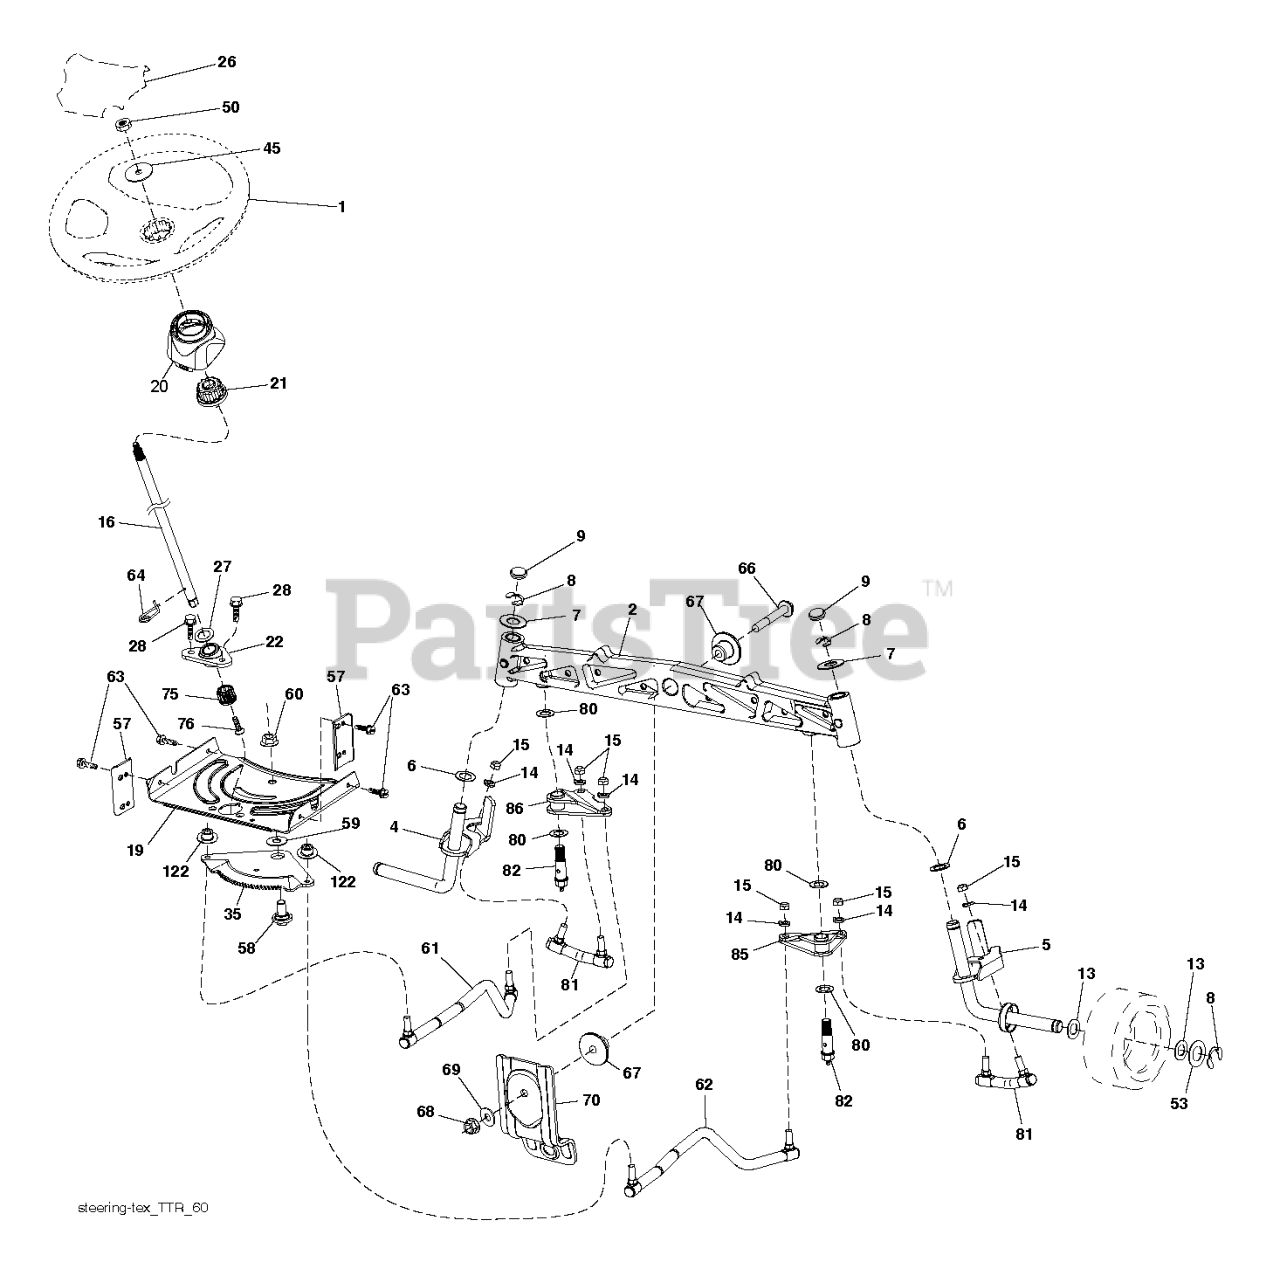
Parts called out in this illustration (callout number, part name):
1	WHEEL.STEERING.HARD.RIM.BLAC
2	RP SUBASM.AXLE.CAST.NZTR.
4	SPINDLE WELDMENT.SPINDLE.LH.15
5	SPINDLE WELDMENT.SPINDLE.RH.15
6	Bearing Race Thrust Harden (AYP part number)
7	Washer 25/32 x 1-5/8 x 16 Gauge (AYP part number)
8	Ring, Klip #T5304-75 (AYP part number)
9	Cap Spindle Fr Top Blk (AYP part number)
13	Washer 25/32 x 1-1/4 x 16 Gauge (AYP part number)
14	SLW 3/8 STD
15	Nut, Crownlock 3/8-24 (AYP part number)
16	SHAFT.STEER.2HIGH.SPLND.PLATED
19	PLATE.STEER.DDL.NLT/NG
20	BOOT.STRNG.PREDATOR.YT/GT.428
21	ADAPTER.WHEEL.STEER.SPLND.ALUM
22	BEARING.SHAFT.STEER.LOWER.625
26	INSERT, WHEEL STEERING
27	Washer 21/32 x 1 x 16 Gauge (AYP part number)
28	SCREW, 3/8-16X3/4
35	GEAR GEAR.SECTOR.TEX.NZTR
45	WASHER.3/8ID.2-3/8OD.12GA.PLTD
50	NUT LOCK FLG 3/8-16 UNC
53	WASHER.HARDENED
57	BRACKET.UPSTOP.TEX
58	BOLT.SHOULDER.SECTOR.P
59	WASHER.THURST.SECTOR.S
60	NUT FLANGE LOCK 5/8-11
61	LINK SUBASM.LINK.DRAG.LH.NZTR
62	TUBE TUBE
63	SCREW
64	RETAINER.CLIP.SPRING.S
66	BOLT HEX FGHD 7/16-14 X 3 SERR
67	BUSHING.PM.FRONT AXLE
68	NUT.LOCK.FLANGE.7/16
69	WASHER.1.5X.505X.118
70	BRACKET.FRT.DECK.SUSP.RR.MT431
75	PINION.ZINC PLATED
76	SCREW HEAD SOCKET LRVB
80	Washer, Thrust 5/8 x 1.10 x 1/32 (AYP part number)
81	LINK SUBASM.LINK.CROSS.NZTR
82	SUBASM;PIVOT;BOLT;NZTR
85	PIVOT SUBASM.PIVOT.RH.NZTR
86	PIVOT SUBASM.PIVOT.LH.NZTR
122	CAP.GEAR.SECTOR.TEX
